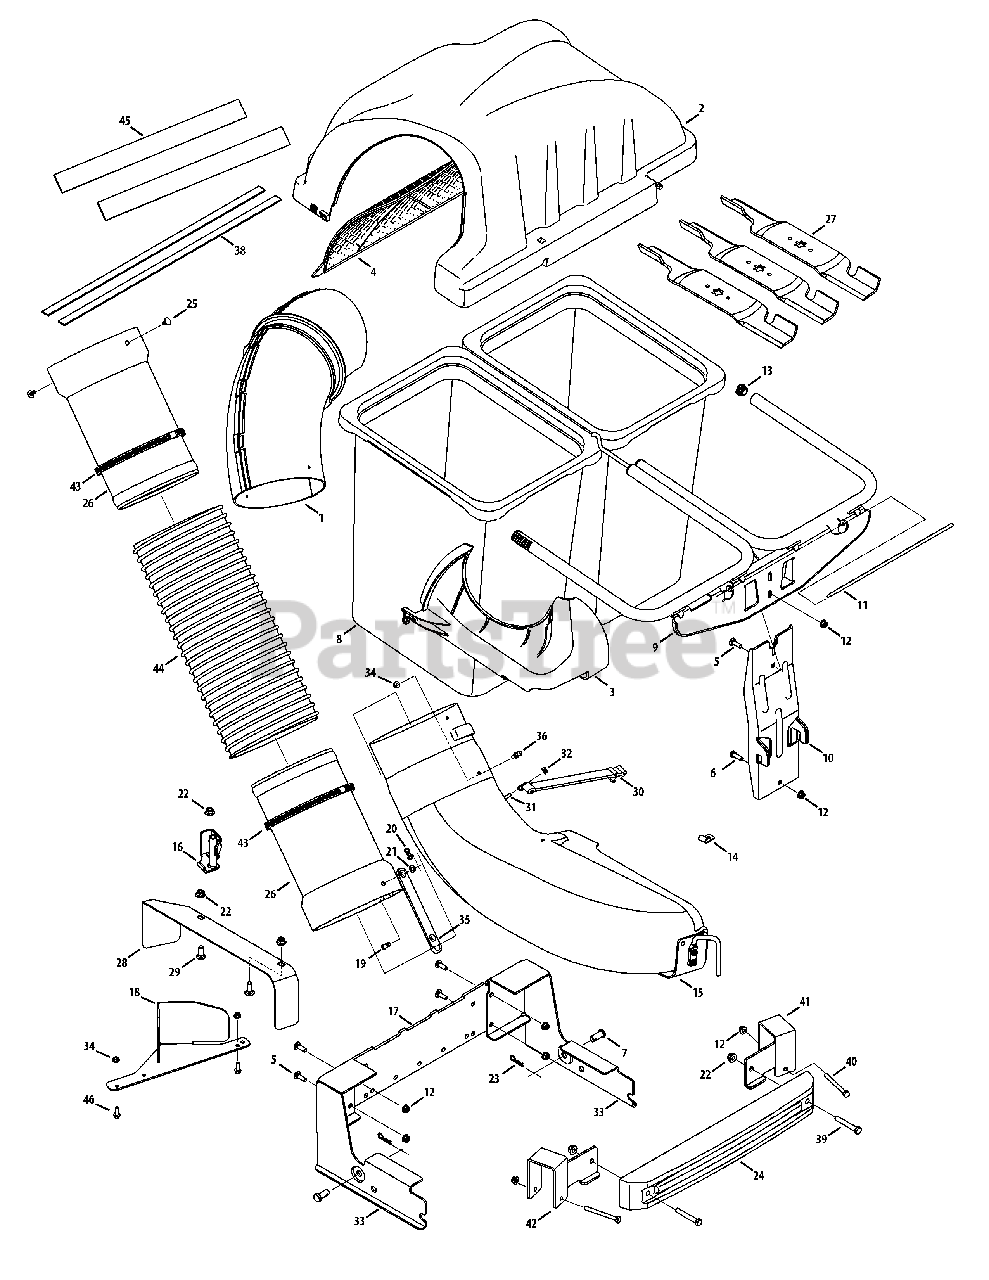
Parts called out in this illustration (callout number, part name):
1	Upper Chute Assembly
2	Twin Bagger Cover
3	Upper Chute Support
4	Bagger Cover Screen
5	Carriage Screw, 5/16-18 x 1.00"
6	Hex Head Screw, 5/16-18 x .75"
7	Clevis Pin, .50" Dia. x .78 Lg.
8	Grass-bag Assembly
9	Twin Bag Support Assembly
10	Vertical Support Bracket
11	Cover Hinge Pin
12	Flange Lock Nut, 5/16-18
13	End Plug
14	Retainer Hook
15	Discharge Chute Elbow
16	Chute Stop-Bracket
17	Universal Mounting Bracket
18	Deck Baffle
19	Clevis Pin, 5/16 x 3/4
20	Bow-Tie Cotter Pin
21	Flat Washer, .344 x .620 x .033
22	Flange Lock Nut, 3/8 - 16
23	Cotter Pin, .080 x 1.5625 Internal
24	RZT Bagger Weight
25	Ratchet Clip, .250
26	Bagger Chute Adapter, 7 In.
27	Blade, 18.50 Lg., High Lift
28	Chute Discharge Plate
29	Carriage Bolt, 3/8-16 x 1.00
30	Chute Strap
31	Hex Head Screw, 1/4-20 x .75
32	Flange Lock Nut, 1/4 - 20
33	RZT Mounting Assembly
34	Flange Lock Nut, 1/4-20
35	Chute Strap
36	Grass-catcher Pin
37	Machine Screw, 1/4-20
38	Adhesive Strip
39	Hex Bolt, 3/8 - 16 x 2.50
40	Hex Bolt, 5/16 - 18 x 2.50
41	Weight Mounting Bracket, RH
42	Weight Mounting Bracket, LH
43	Adj. Hose Clamp
44	Flexible Chute Extension
45	Wide Adhesive Rubber Strip
46	Hex Flange Bolt, 1/4-20x.75
